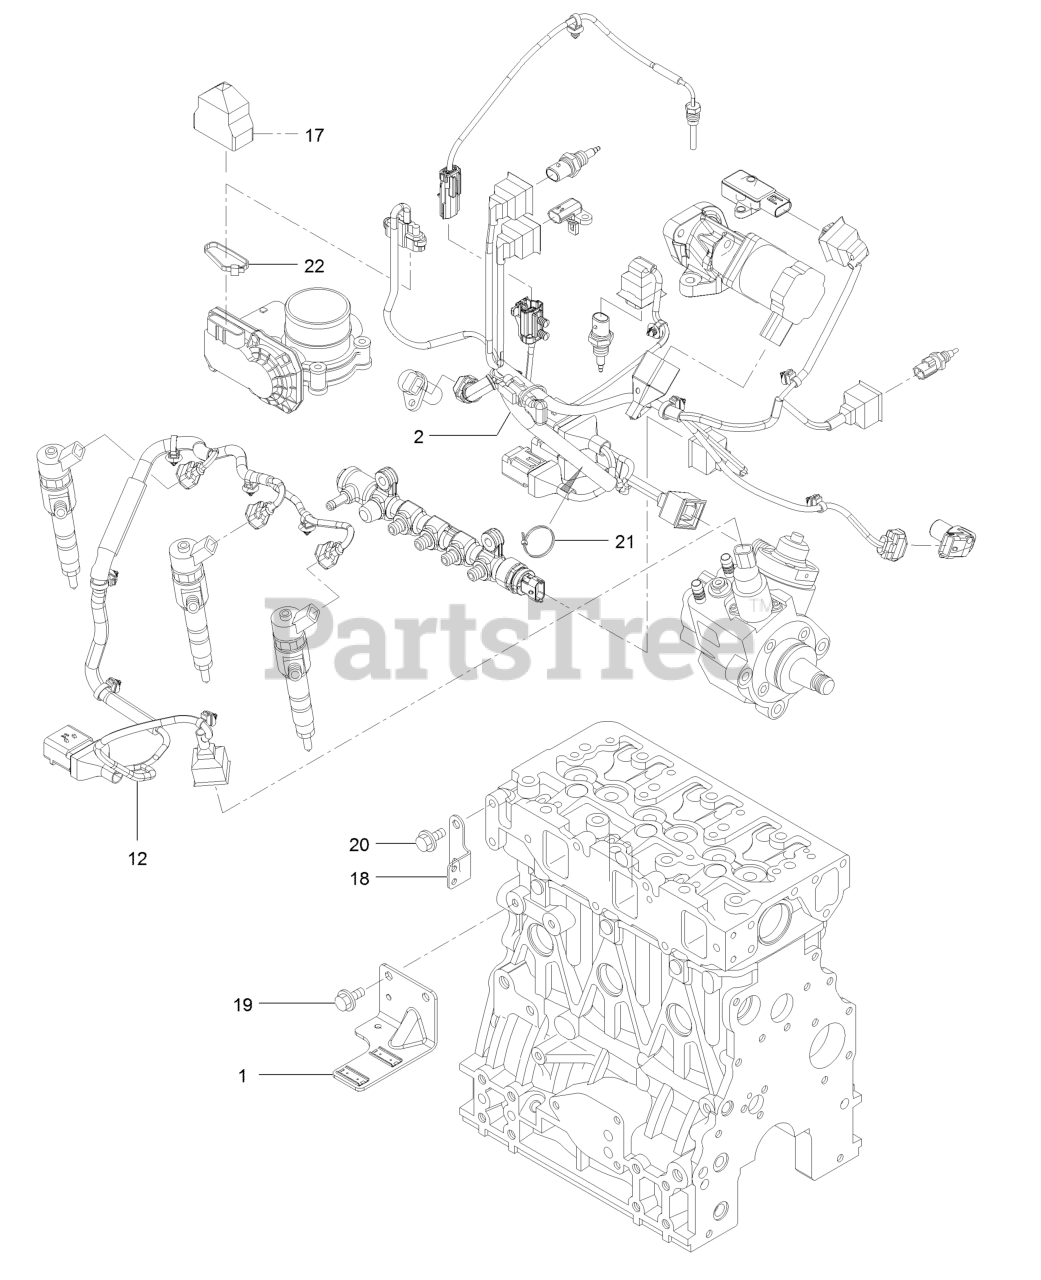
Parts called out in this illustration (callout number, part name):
1	Bracket-Connector
2	Harness
12	Harness
17	Boot-Cap
18	Bracket-Harness
